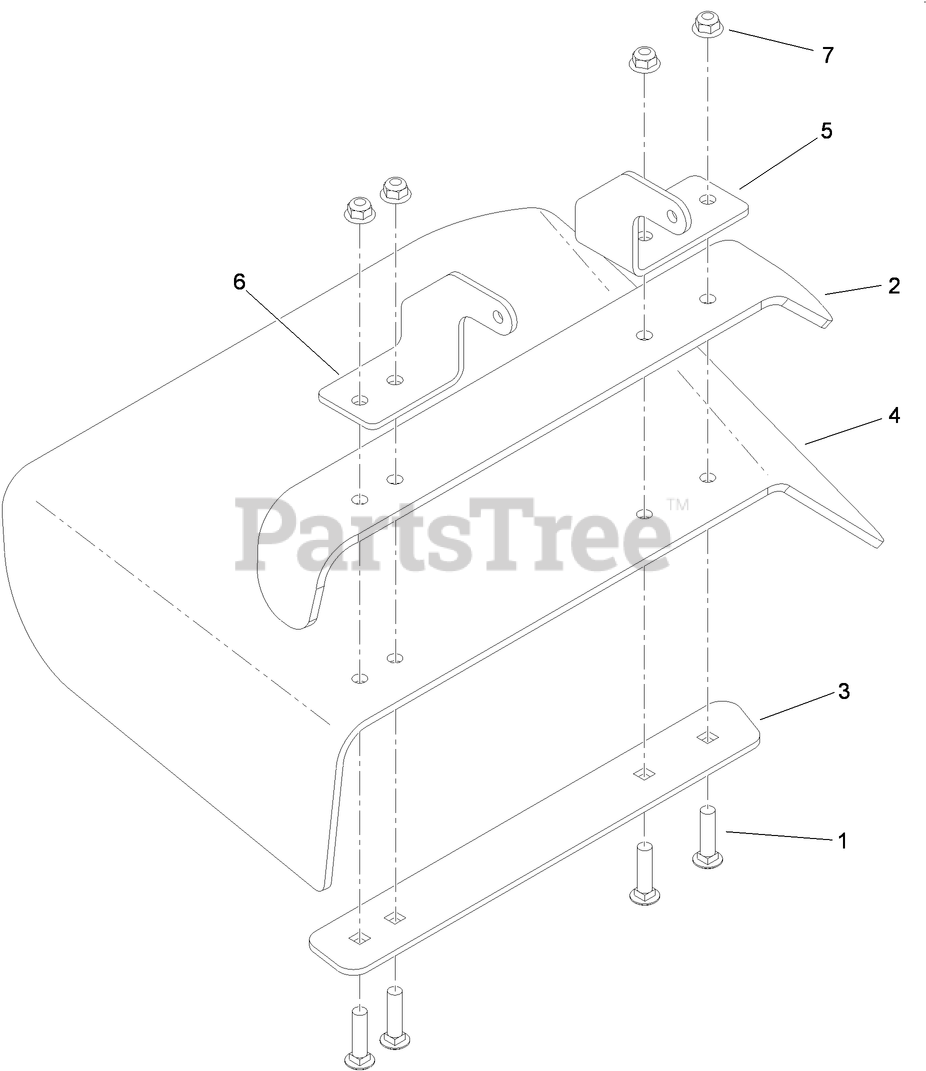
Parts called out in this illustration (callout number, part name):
1	SCREW-CARR
2	DEFLECTOR
3	STRAP-DISCHARGE
4	DEFLECTOR-RUBBER
5	BRACKET-HINGE, REAR
6	BRACKET-HINGE, FRONT
7	NUT-HF, NI
